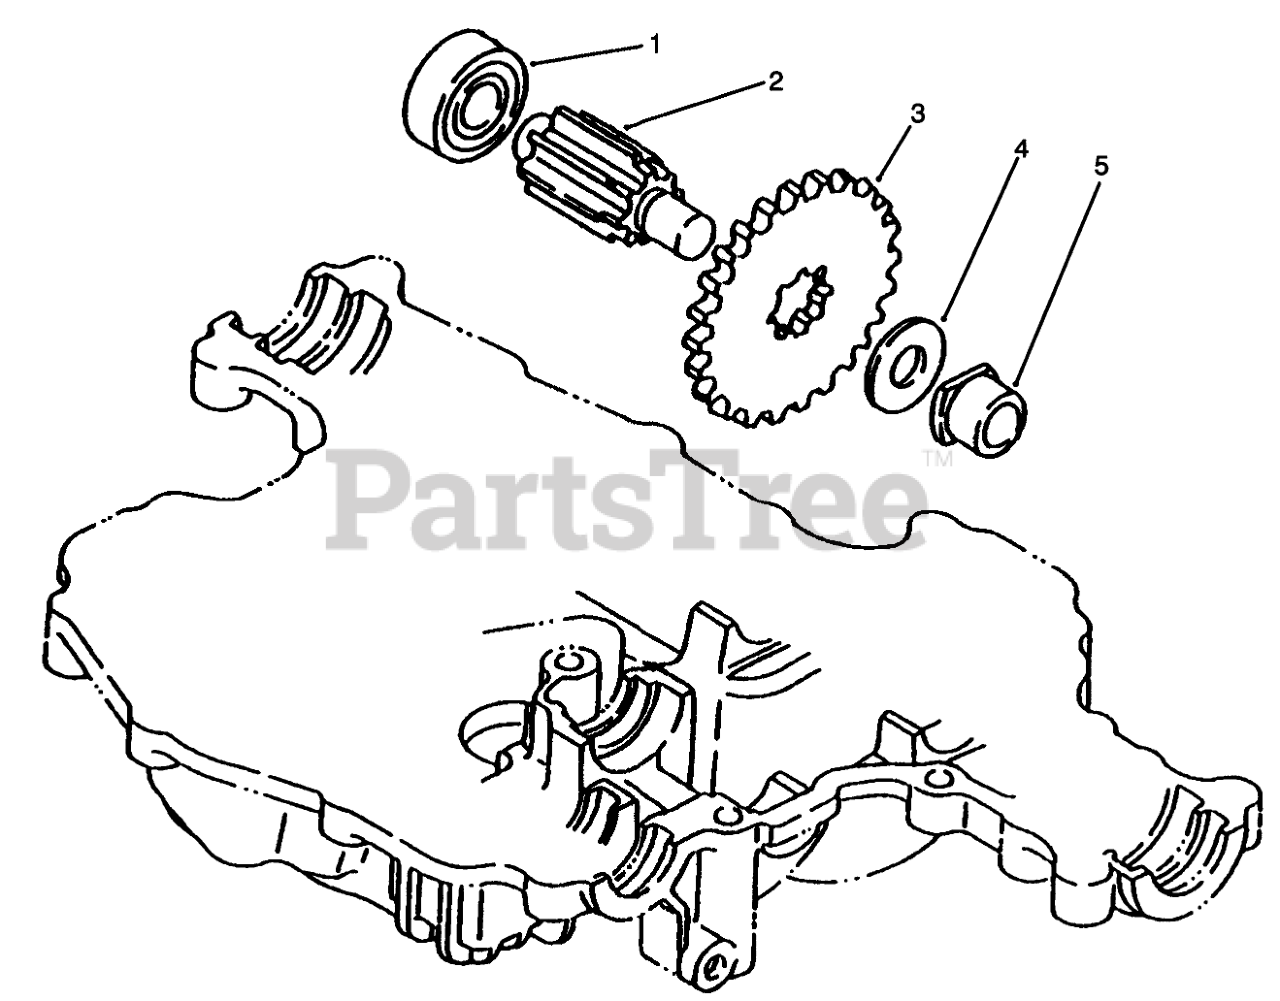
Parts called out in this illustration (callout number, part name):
1	Bearing (Only On: 72043, 72063, 72103)
2	Shaft-Final Pinion (Only On: 72043, 72063, 72103)
3	Gear-Final Shaft (Only On: 72043, 72063, 72103)
4	Washer (Only On: 72043, 72063, 72103)
5	Bushing (Only On: 72043, 72063, 72103)
